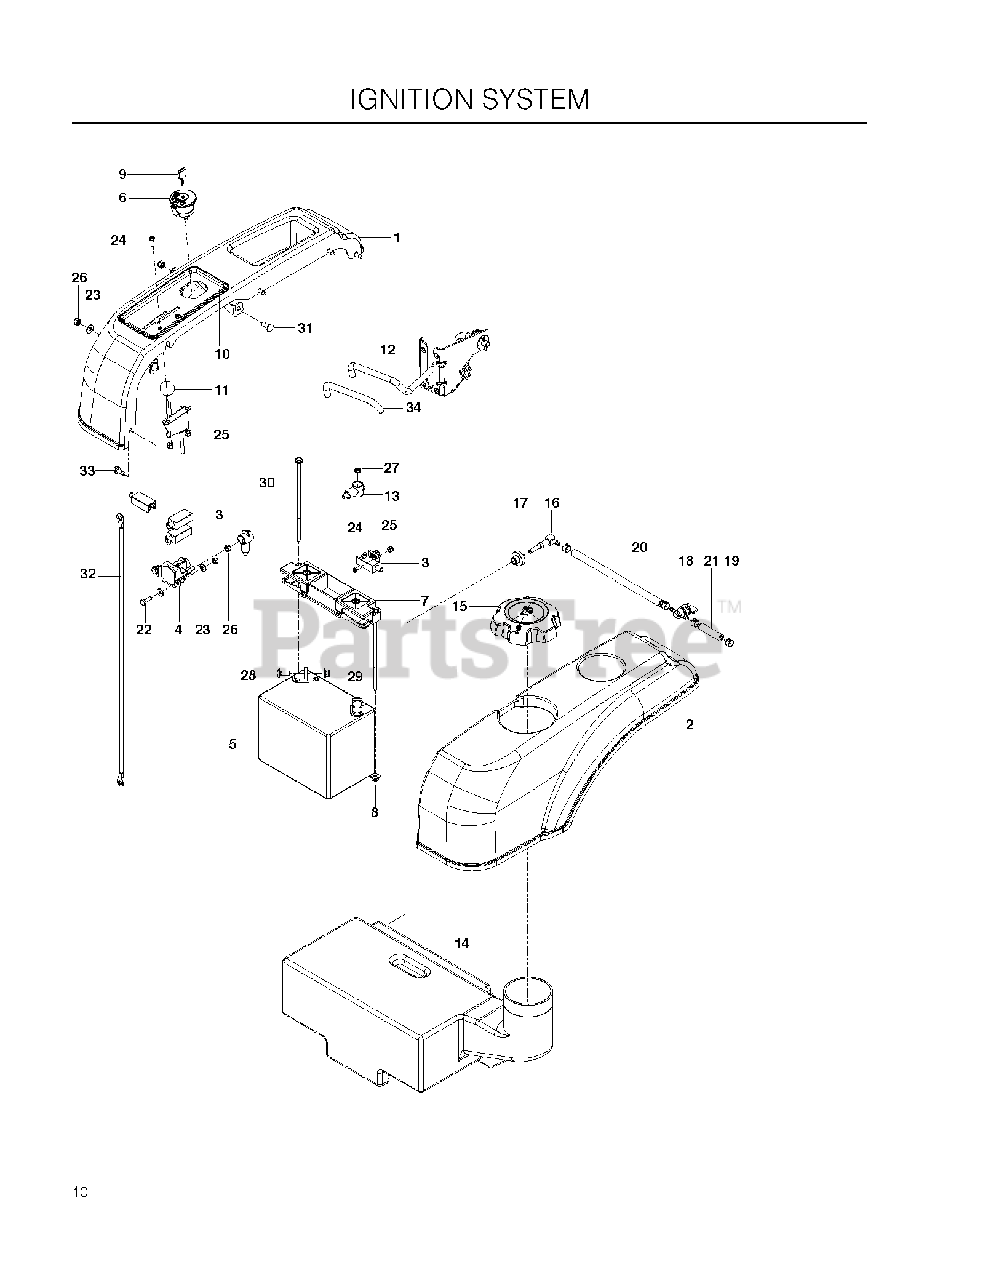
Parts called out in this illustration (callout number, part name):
1	FENDER RH
2	FENDER LH
3	SWITCH, INTERLOCK
4	SOLENOID
5	BATTERY, 12 V 330 AMP TBR
6	IGNITION SWITCH
7	BATTERY HOLD DOWN
8	PUSH NUT-NYLON
9	KEY
10	MOUNT, CONTROLS, BLK
11	THROTTLE CABLE
12	ASM, CLUTCH ENGAGE, W/CBL
13	TERMINAL COVER-SM
14	FUEL TANK
15	FUEL CAP, GENERIC
16	ELBOW W/FILTER
17	TANK FITTING
18	FUEL VALVE
19	HOSE CLAMP
20	HOSE 1/4 X 8
21	HOSE 1/4 X 2"
22	HCS 1/4C X 3/4 HCS
23	WASHER 1/4 SAE
24	SCREW #10-24 X 5/8
25	NUT 10-24 NYLOC
26	NUT 1/4-20 NYLOC
27	JAM NUT 1/4C
28	BOLT 5/16C X 3/4" CARRIAGE
29	5/16-18 NYLOC FLANGE NUT
30	BOLT - 1/4-20 X 7.5
31	RHSNB 1/4C X 3/4
32	BATTERY CABLE, NEGATIVE
33	SCREW 1/4 X 5/8
34	GRIP, CLUTCH, 3/8"
